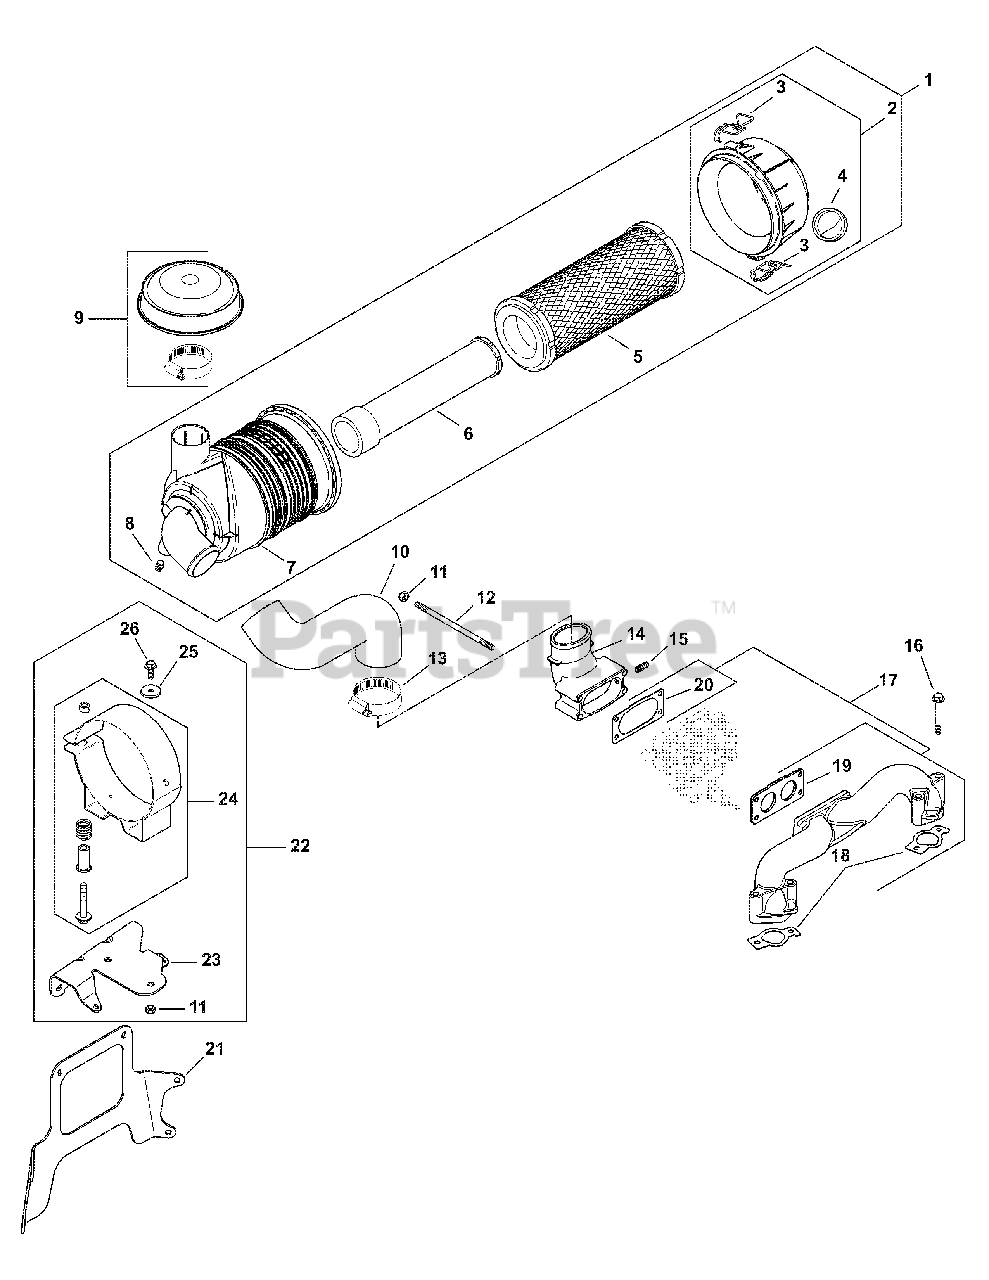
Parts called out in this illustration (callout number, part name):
1	Cleaner, Air-Canister
2	Cover Assembly, Air Cleaner
3	Clip
4	Valve, Dust Ejector
5	Element, Air Filter-Primary
6	Element, Air Filter-Safety
7	Housing, HD Air Cleaner
9	Hood, Air Cleaner
10	Hose, Air Cleaner
11	Nut, Lock M6x1.0
12	Stud, M6x1.0x122
14	Kit, Air Cleaner Elbow
15	Fitting, Barbed
16	Screw, FLG M6x1.0x55
17	Kit, Intake Manifold
18	Gasket, Intake Manifold
19	Gasket, Carburetor
20	Gasket, Air Cleaner Elbow
21	Bracket, Main Support
22	Bracket, Air Cleaner Sub Assy
23	Bracket, Air Cleaner Mounting
24	Bracket Assy, Air Cleaner
25	Washer, Flat 1/4"
26	Screw, FLG M6x1.0x16
